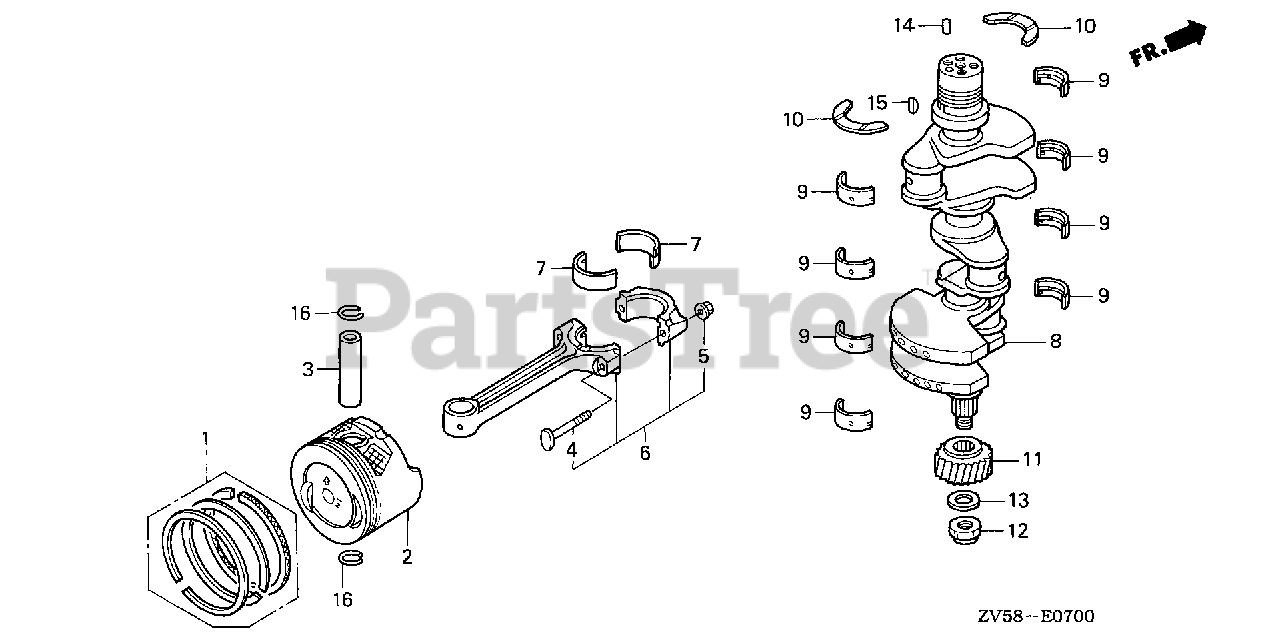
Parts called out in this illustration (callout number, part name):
1	RING SET, PISTON
1	RING SET, PISTON (OS 0.25)
2	PISTON (STD)
2	PISTON (OS 0.25)
3	PIN, PISTON
4	BOLT, CONNECTING ROD
5	NUT, CONNECTING ROD
6	ROD SET, CONNECTING
7	BEARING A, CONNECTING ROD (BLUE) (DAIDO)
7	BEARING B, CONNECTING ROD (BLACK) (DAIDO)
7	BEARING C, CONNECTING ROD (BROWN) (DAIDO)
7	BEARING D, CONNECTING ROD (GREEN) (DAIDO)
7	BEARING E, CONNECTING ROD (YELLOW) (DAIDO)
7	BEARING F, CONNECTING ROD (PINK) (DAIDO)
7	BEARING G, CONNECTING ROD (RED) (DAIDO)
8	CRANKSHAFT
9	BEARING A, MAIN (BLUE) (DAIDO)
9	BEARING B, MAIN (BLACK) (DAIDO)
9	BEARING C, MAIN (BROWN) (DAIDO)
9	BEARING D, MAIN (GREEN) (DAIDO)
9	BEARING E, MAIN (YELLOW) (DAIDO)
9	BEARING F, MAIN (PINK) (DAIDO)
9	BEARING G, MAIN (RED) (DAIDO)
10	WASHER, THRUST
11	GEAR A, PRIMARY DRIVE (26T) (WHITE)
11	GEAR B, PRIMARY DRIVE (26T) (BLUE)
11	GEAR C, PRIMARY DRIVE (26T) (YELLOW)
11	GEAR A, PRIMARY DRIVE (28T) (WHITE)
11	GEAR B, PRIMARY DRIVE (28T) (BLUE)
11	GEAR C, PRIMARY DRIVE (28T) (YELLOW)
12	NUT, FLANGE (22MM)
13	WASHER (22MM)
14	PIN, DOWEL (6X10)
15	KEY, WOODRUFF (25X14)
16	CLIP, PISTON PIN (18MM)
